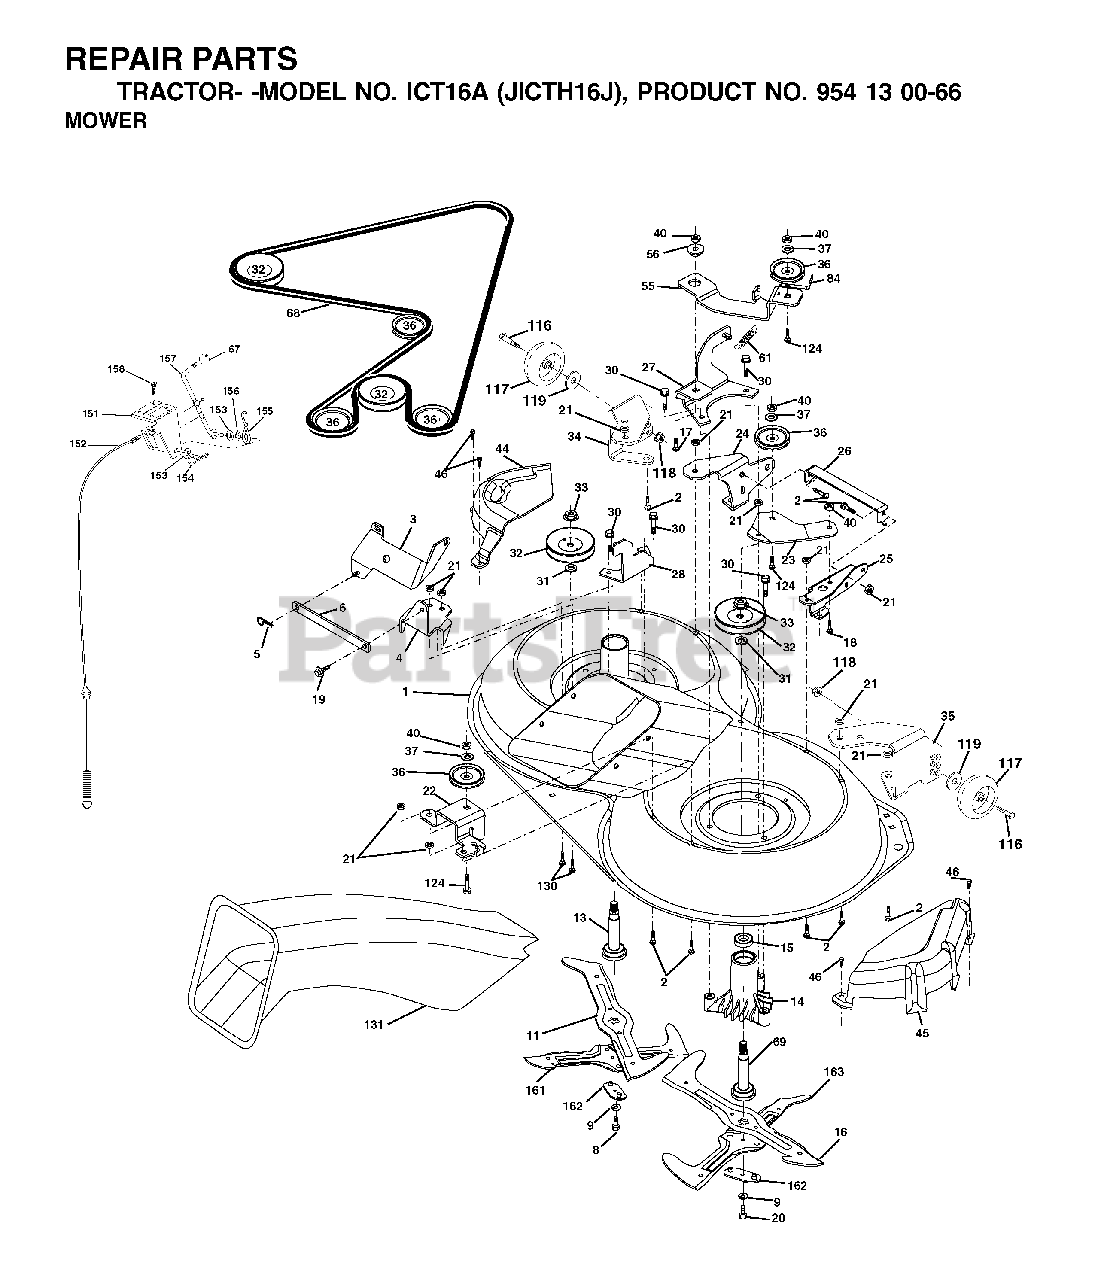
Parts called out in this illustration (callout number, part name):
1	MOWER HOUSING, DECK
2	BOLT
3	BRACKET
5	RETAINER-SPRNG RB
6	BAR SWAY
9	LOCKWASHER
10	WASHER.BLADE
11	BLADE-LH 5PT STAR(CTH130)
13	SHAFT ASM VENT
14	HSG MANDREL
16	BLADE RH 6PT STAR(CTH130)
17	BOLT.3/8-14X1.25
19	BOLT SHD 5/16-18
21	LOCKNUT
24	BRACKET
25	BRACKET
26	BRACE
28	BRACKET
30	SCREW, WASHER HEAD
31	WASHER
32	PULLEY, MANDREL
33	NUT, FLG TOPLOCK 9/16"
36	PULLEY.IDLER.4.25
40	LOCKNUT
45	MANDREL COVER
46	SCREW.1/4-20X5/8
55	ARM IDLER
56	SPACER.RETAINER.MOWER
61	SPRING.TENSION.BELT
67	KNOB T (3/8 HOLE)
68	HEX-BELT
69	SHAFT.ASM.W/LWR.BRG.RH.THREAD
84	KEEPER, BELT IDLER
116	BOLT, SHOULDER
117	WHEEL GAGE DONUT
118	LOCKNUT
119	WASHER
124	BOLT.3/8-16X1.50
131	CHUTE BAGGER
151	BRACKET, CLUTCH CABLE
153	WASHER FLAT 3/8"
154	SPRING RETAINER
155	SPRING RETENTION LEVER
156	SPACER CLUTCH CABLE
157	ROD CLUTCH CABLE 3/8"
158	SCREW
